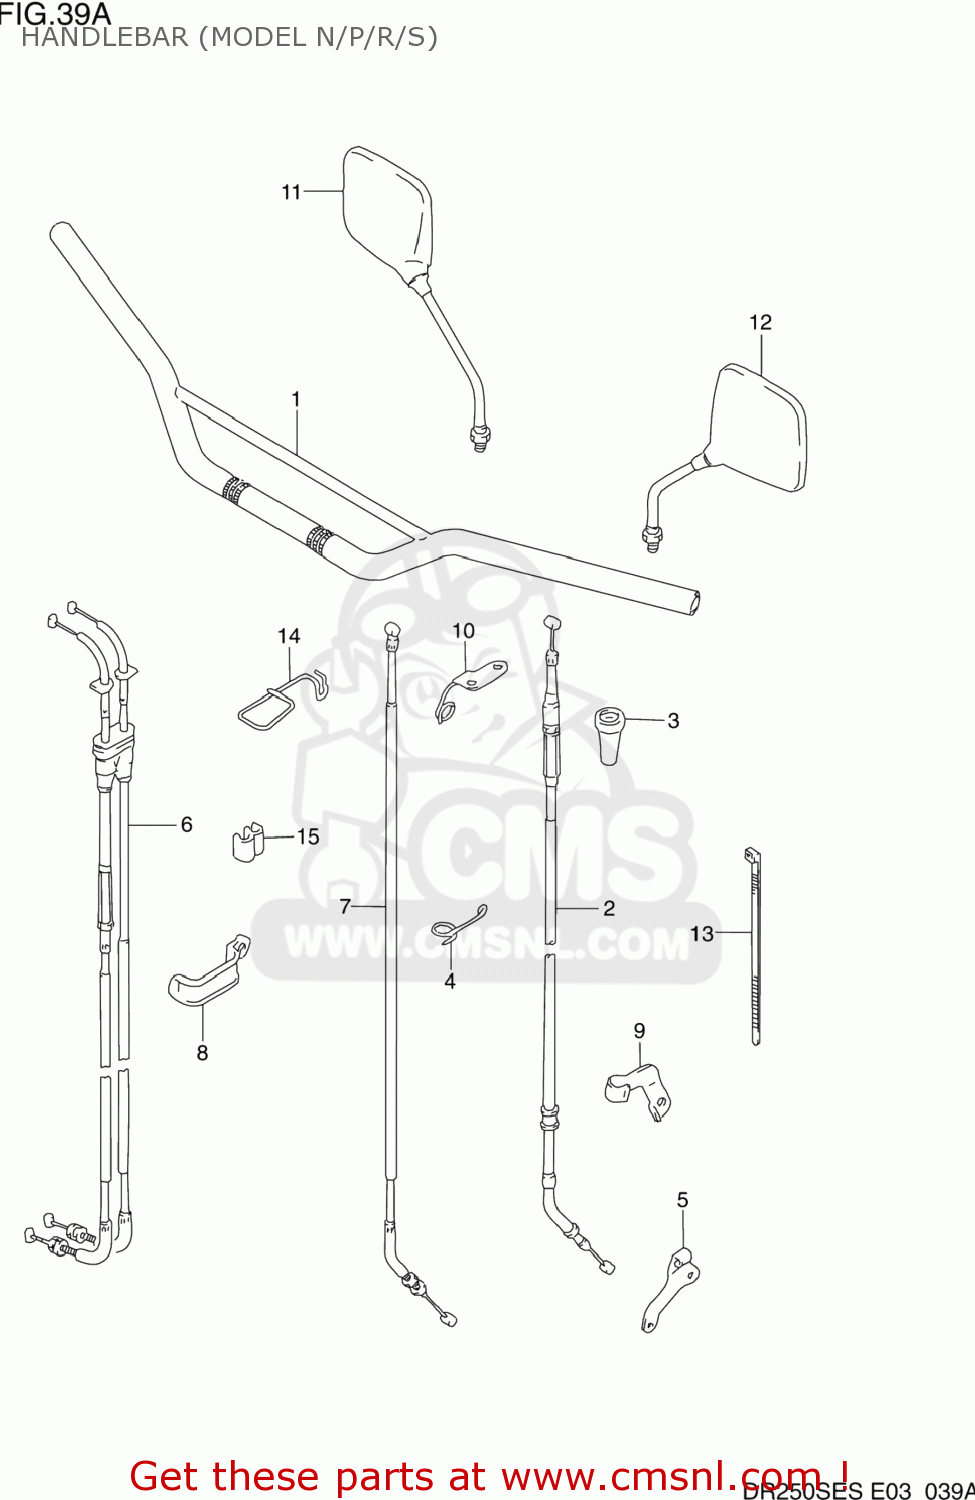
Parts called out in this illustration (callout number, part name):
1	HANDLEBAR
2	CABLE ASSY,CLUTCH
3	BOOT,CLUTCH CABLE
4	GUIDE,CLUTCH CABLE
5	STOPPER,CLUTCH CABLE
6	CABLE ASSY,THROTTLE
7	CABLE ASSY DECOMP
8	CLAMP
9	CLAMP,CLUTCH CABLE
10	GUIDE,CABLE
11	MIRROR ASSEMBLY,RIGHT
12	MIRROR ASSEMBLY,LEFT
13	CLAMP(L:100)
14	GUIDE,CLUTCH CABLE
15	CLIP
